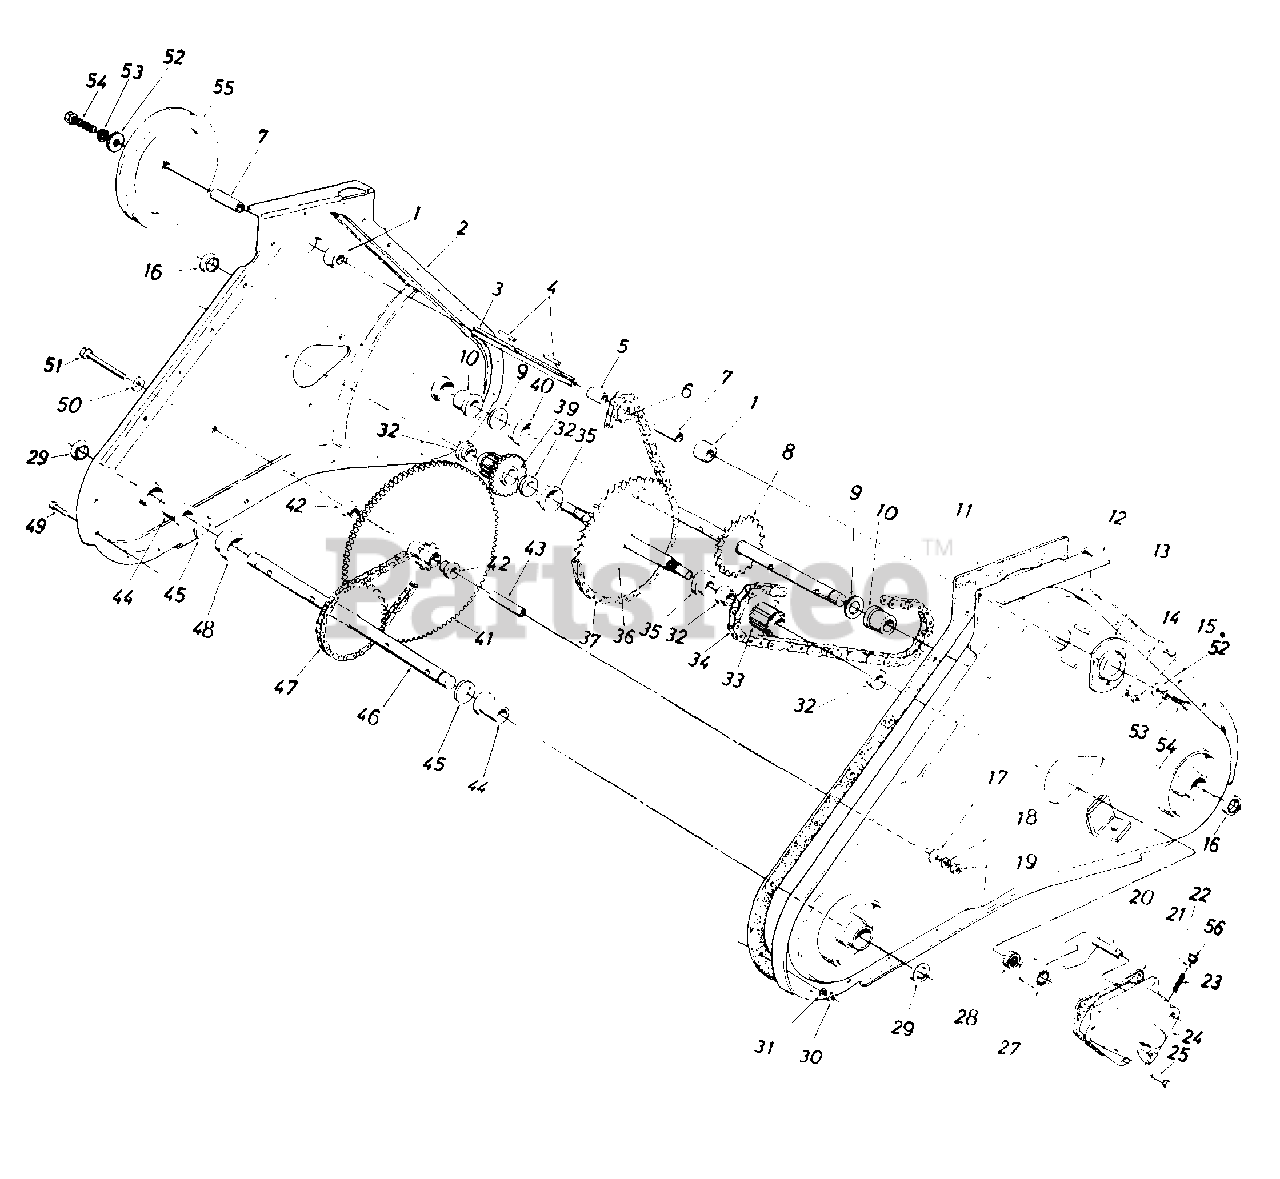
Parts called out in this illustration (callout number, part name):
1	Ball Bearing .62" I.D. x 1.38" O.D. x .44
2	Chain Case R.H. Half
3	Input Shaft .62" Dia.
4	Sq. Key 3/16" x 3/16" x .75" Lg.
5	Spacer .637" I.D. x .781" O.D. x .85" Lg.
6	Sprocket 9 Tooth x .62" Shaft
7	Spacer .637" I.D. x .781" O.D. x 1.44" Lg.
8	Tine Shaft Ass'y.
9	Fl-Wash. 1.28" I.D. x 1.62" O.D.
10	Flange Bearing 1.25" I.D.
11	Gasket - Housing
12	Chain Case L.H. Half
13	Bearing Housing 1-3/8" O.D.
14	L-Wash. 1/4" I.D.
15	Hex Nut 1/4-28 Thd.
16	Seal 1.25" I.D.
17	Belleville Wash.
18	L-Wash. 3/8" I.D.
19	Hex Cent. L-Nut 3/8-24 Thd.
20	Shift Yoke Ass'y. - L.H.
21	Gasket - Shift Housing
22	Ball Detent .250 Dia.
23	Compression Spring
24	Shift Housing - L.H.
25	Hex Tap-Tite 5/16-18 x .75" Lg.
27	Clutch Dog
28	Clutch Dog Driver
29	Seal 1.0" I.D. x 1.38" O.D.
30	Hex Nut 1/4-28 Thd.
31	L-Wash. 1/4" I.D.
32	Flange Brg. 1.00" I.D.
33	Sprocket Brg. Sleeve Ass'y.
34	#50 Chain - 5/8" Pitch x 50 Links - Endless
35	Stepped Spacer 1.0" I.D. x 1.75" O.D.
36	Clutch Shaft Ass'y.
37	#420 Chain 1/2" Pitch x 58 Links - Endless
39	Gear Bearing - Sleeve Ass'y.
40	Spacer 1.25" I.D. x 2.0" O.D. x .68" Lg.
41	Sprocket and Gear Ass'y.
42	Flange Brg. .628" I.D. x .753" O.D.
43	Hub Sleeve .38" I.D. x .625" O.D.
44	Flange Brg. 1.00" I.D. x 1.188" O.D.
45	Fl-Wash. 1.0" I.D. x 1.62" O.D.
46	Axle Shaft Ass'y.
47	#420 Chain 1/2" Pitch 46 Links - Endless
48	Spacer 1.0" I.D. x 2.0" O.D.
49	Hex Bolt 1/4-28 x .62" Lg.
50	Belleville Wash.
51	Hex Bolt 3/8-24 x 2.75" Lg.
52	Fl-Wash. 5/16" I.D.
53	L-Wash. 5/16" I.D.
54	Hex L-Bolt 5/16-24 x .75" Lg.
55	Input Pulley - Chain Case
56	Cap Plug .250" Dia.
